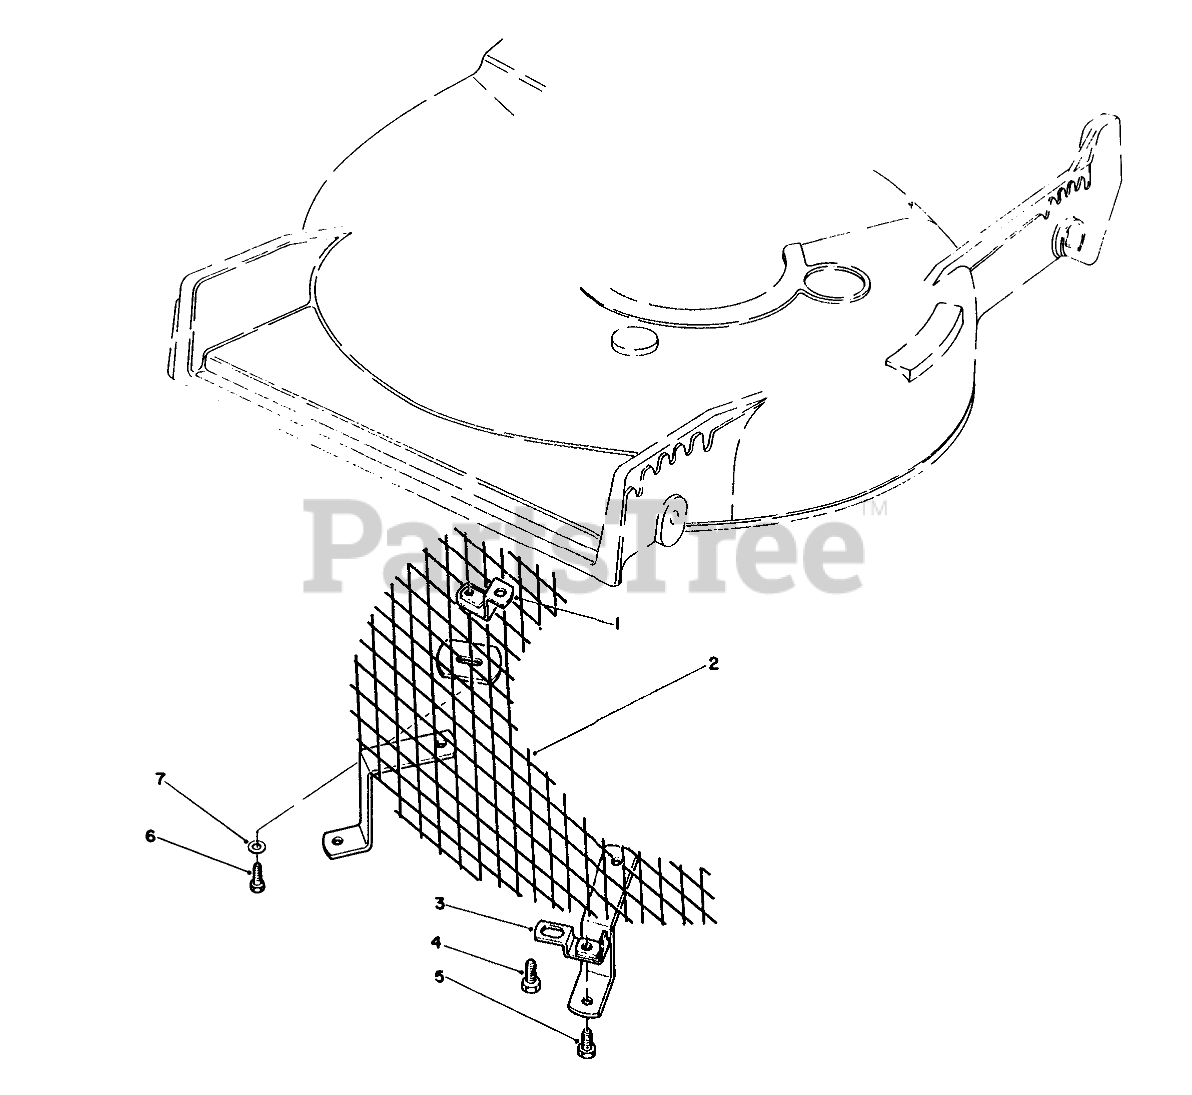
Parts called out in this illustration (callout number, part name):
1	BRACKET WA
2	SCREEN WA
3	MTG. BRACKET W.A.
4	SCREW-HWHTF
5	SCREW-HH
6	SCREW-HH
7	WASHER-FLAT
